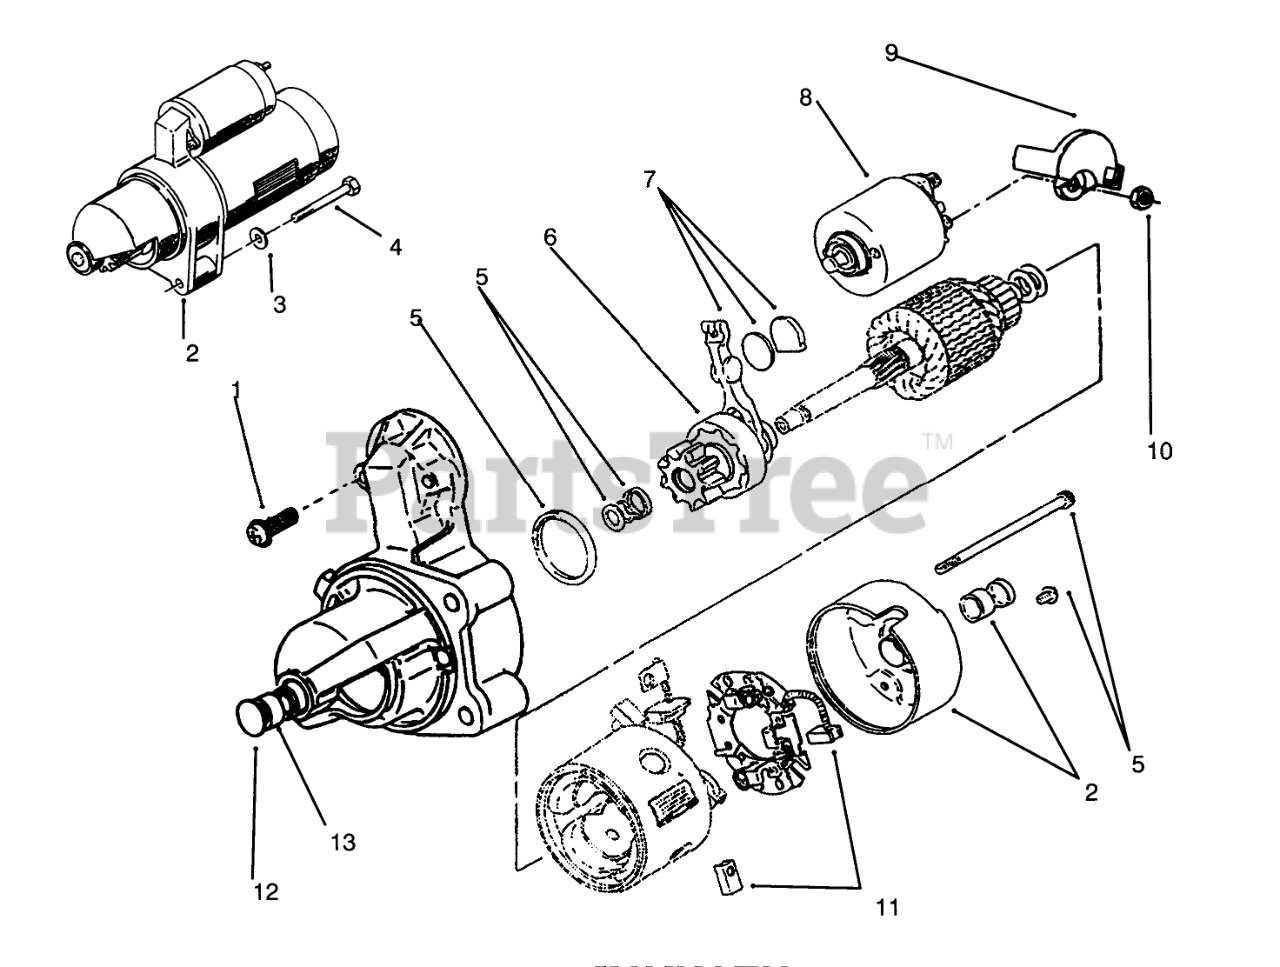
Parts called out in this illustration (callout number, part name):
1	Starter Hdwr Kit (Incl.Solenoid Screws 2]Brush Holder Screws 2], Thru Bolts2],Armature Shims 2], Pinion Stop Collar, & Pinion Retaining Ring)
2	STARTER
3	WASHER
4	SCREW
5	DUST-SEAL KIT
6	Clutch-Starter (Incl. Pinion Gear w/Clutch)
7	Kit-Starter Shift Lever(Incl. Shift Lever, Wear Plate & Rubber Plug)
8	Kit-Starter Solenoid (Incl. Solenoid, Spring, & Plunger)
9	Cap-Starter Solenoid
10	Nut
11	Kit-Starter Brush (Incl.Positive Brush 2] & Negative Brush w/Pigtail)
12	Kit-Bushing (Incl. Front Bushing & Rear Cap w/Bushing)
13	Holder-Starter Brush (Incl. Brush Holder w/Negative Brush)
